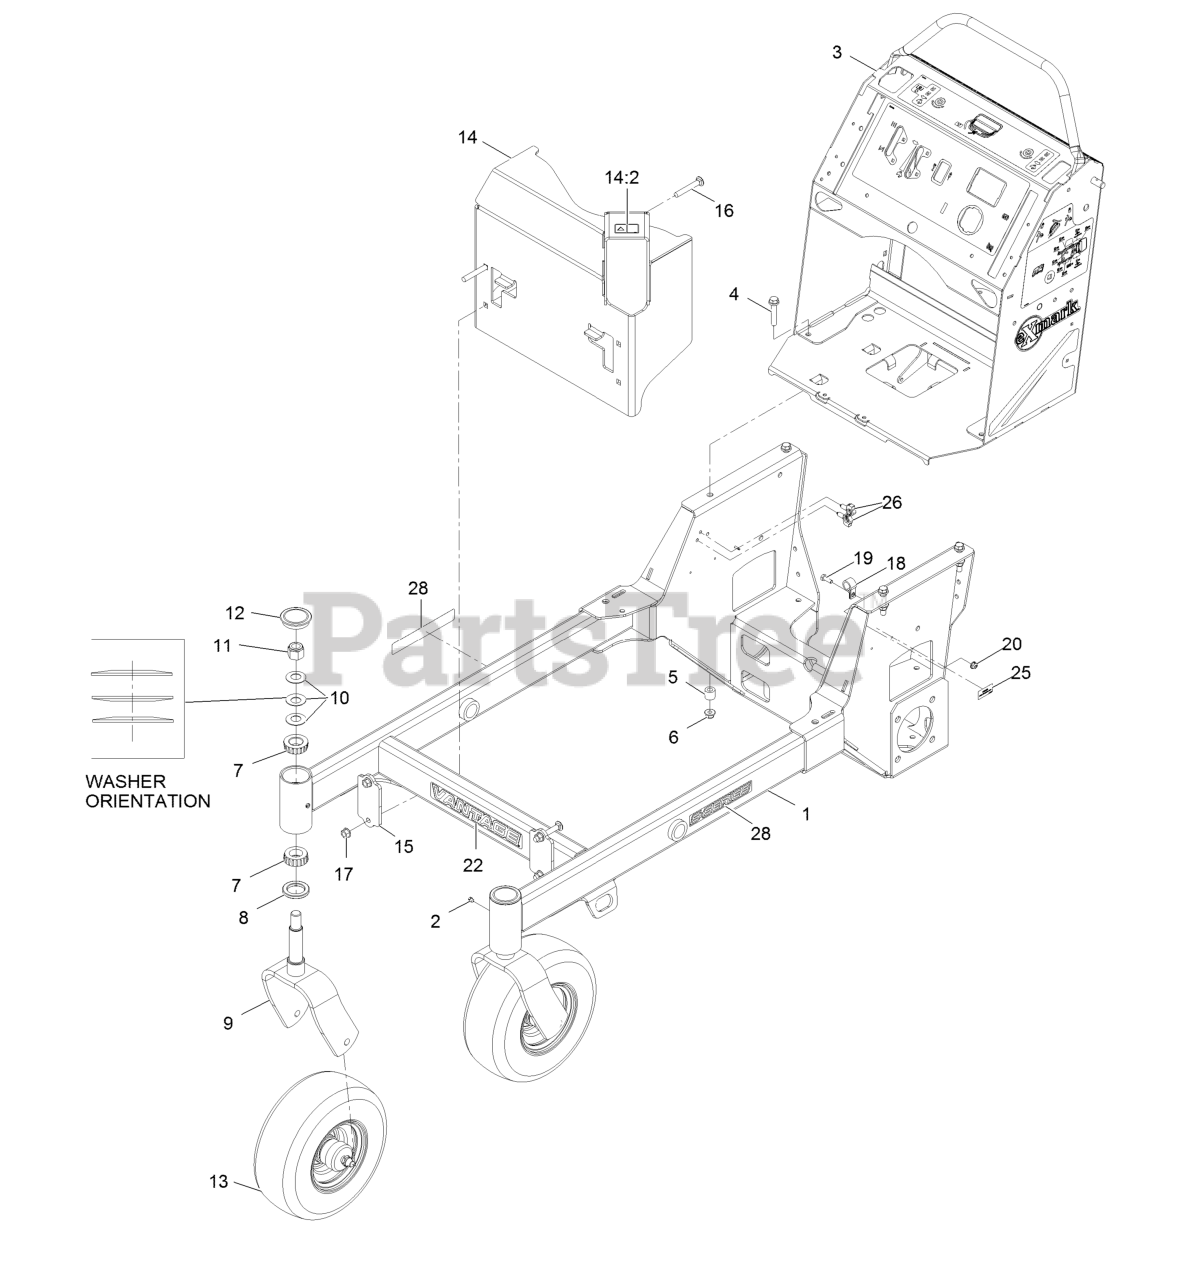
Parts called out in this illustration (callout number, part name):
1	Frame ASM
3	Control Tower ASM
4	Screw-HH Flg 3/8-16 X 2
6	Nut-Nyloc 3/8-16 Flg
7	Cone-Bearing Tapered Roller
8	Seal-Grease
9	Fork-Caster
10	Washer-Spring Disc
11	Nut-Nyloc 3/4-10
12	Cap-Grease
13	Wheel/Tire And Bearing ASM
14	Muffler Guard ASM
14:2	Decal-Warning
15	Bracket-Mounting, Guard
16	Bolt-Carriage 3/8-16 X 2 1/2
17	Nut-3/8-16 Flanged Side Lock
18	Clamp-Cable
19	Screw-HH 1/4-20 X 3/4
20	Nut-Nyloc 1/4-20 Flg
22	Decal-Vantage Logo
25	Decal-Patent
26	Clip-Harness
28	Decal-S-Series
